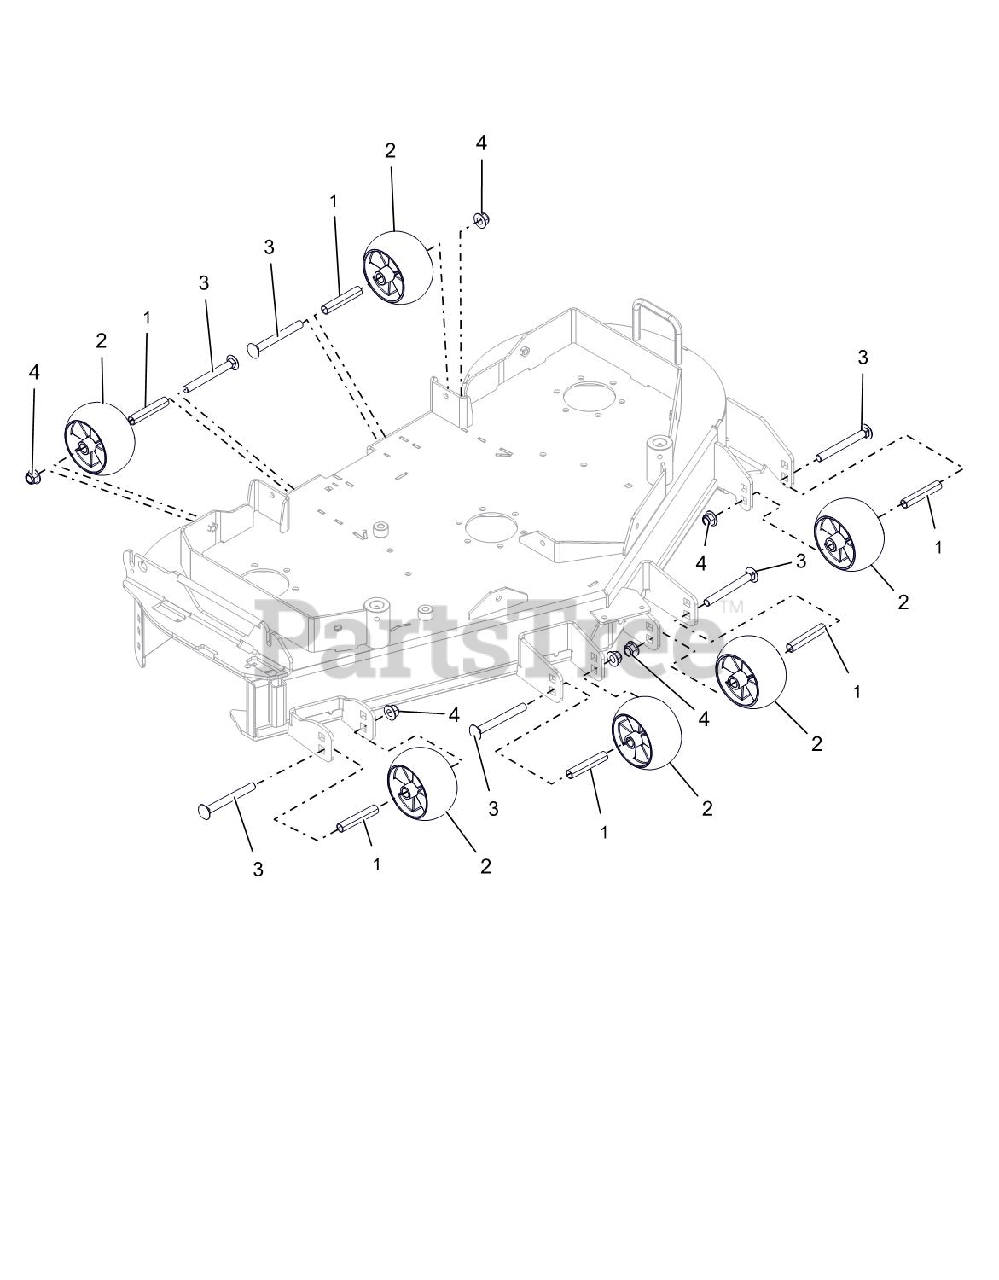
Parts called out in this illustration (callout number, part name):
1	SPACER, .510 X .625 X 3.25
2	ANTI-SCALP WHEEL - 5X3 CTR
3	BLT,RHSN .50-13X4.50 G5 ZCC
4	NUT,LK-NYL-FLG .50-13 G5ZC120
